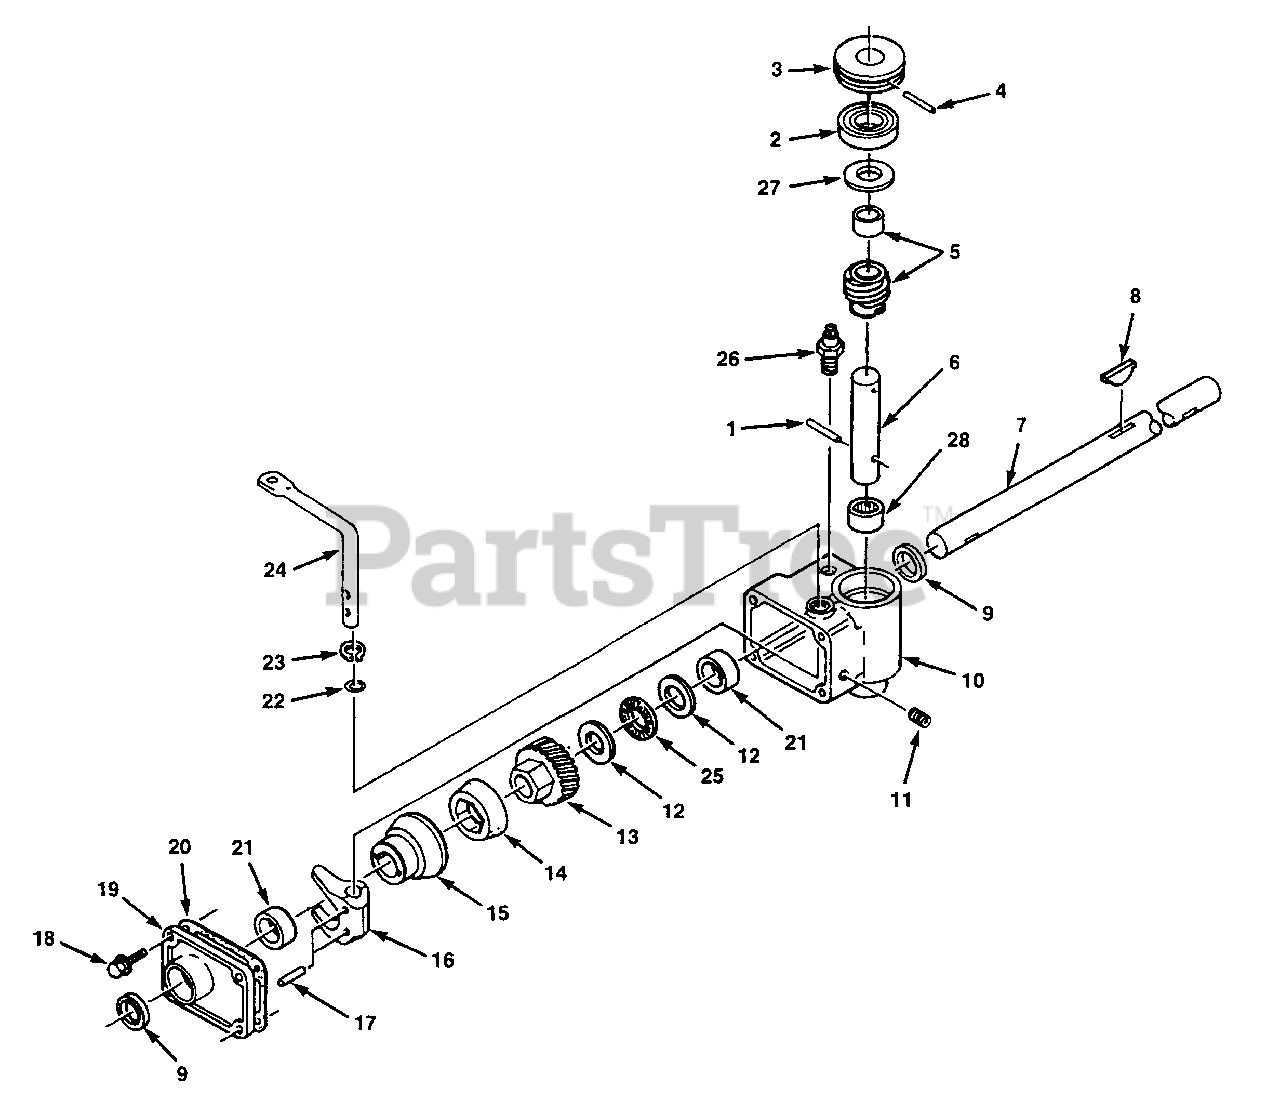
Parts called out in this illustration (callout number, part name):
1	PIN- 3/16 x 7/8
3	PULLEY
4	PIN- 3/32 x 3/4
5	WORM & SPACER
6	SHAFT- Worm
7	SHAFT- Drive
8	KEY- 1/2 x 1/8
10	GEAR REDUCER HOUSING ASSY.
12	RACE- Bearing
13	GEAR- Helical
14	CONE- Friction
15	DRUM- Clutch
16	FORK- Shift
17	PIN- 5/32 x 3/4
18	SCREW- 1/4-20 x 7/8
19	COVER- Gearbox
20	GASKET
21	BUSHING- Sleeve
24	LEVER- Shift
25	BEARING- Thrust
28	BEARING- Needle
